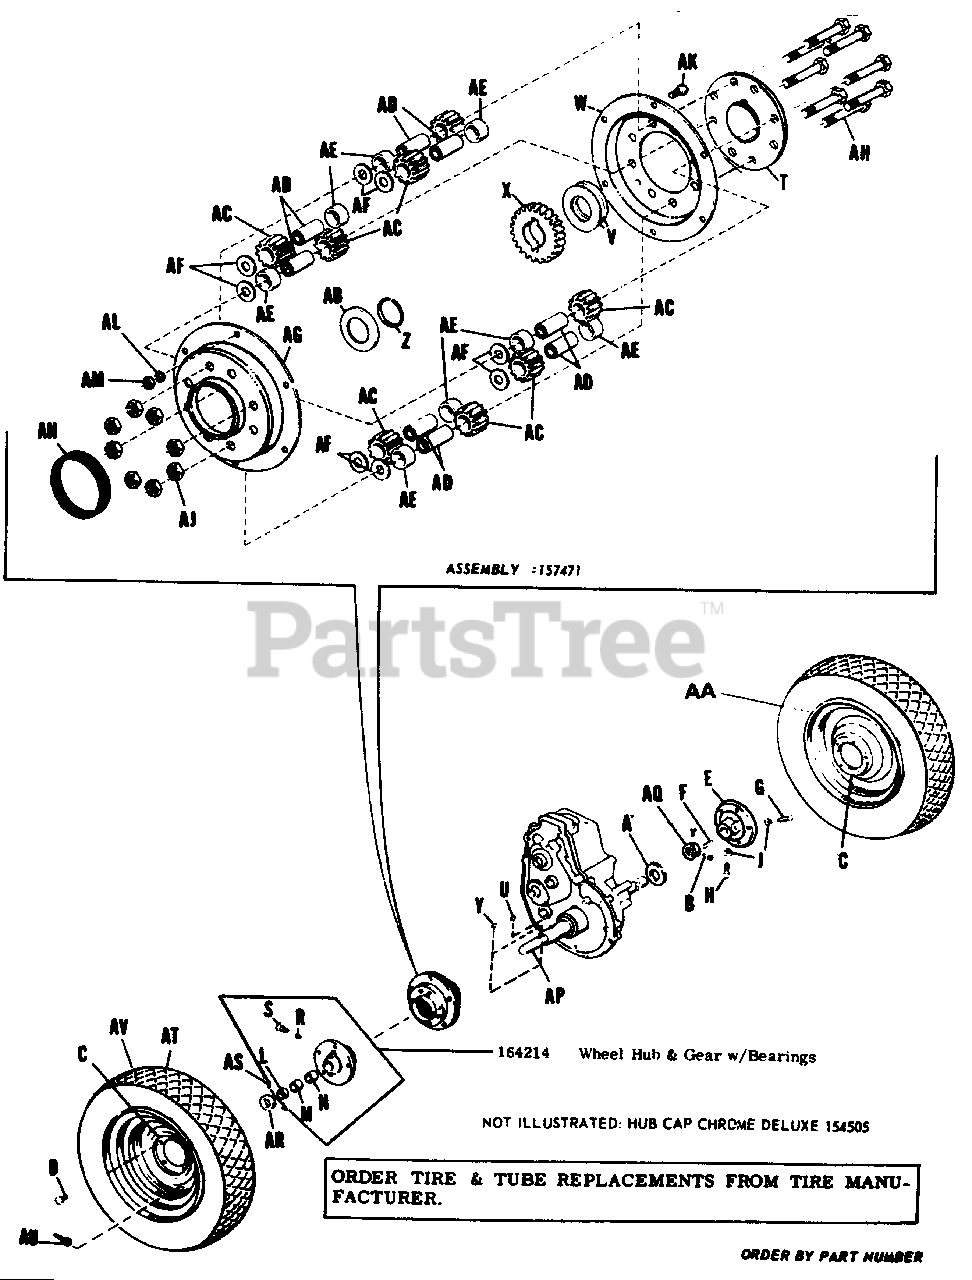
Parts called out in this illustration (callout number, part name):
B	Set Screw, 5/16"-18 x 3/8" Lg.
C	Wheel Drive
E	L.H. Wheel Hub
G	Set Screw, 3/8"-16 x 1 1/2" Lg.
H	Set Screw, 3/8"-16 x 1" Lg.
J	Hex. Jam Nut, 3/8"-16
M	Nylon Bearing
R	Nylon Plug
S	Control Traction Bolt, 7/16"-20 x 1/2" Lg.
T	Differential Carrier
V	Axle Washer
W	Differential Cover
X	Differential Gear
Y	Hi-Pro Key
Z	Retaining Ring
AA	Tube (For Service Only)
AB	Axle Washer
AC	Differential Pinion
AD	Pinion Differential Spindle
AE	Differential Spacer
AF	Plain Washer
AG	Differential Cover
AH	Hex. Cap Screw, 3/8"-16 x 2 1/2"
AJ	Full Lock Hex. Nut, 3/8"-16
AK	Hex. Cap Screw, 1/4 "-20 x 5/8"
AL	Lock Washer, 1/4"
AM	Full Hex. Nut, 1/4"-20
AN	Differential Cover Seal
AQ	Axle Collar
AR	Axle Collar
AS	Set Screw, 5/16"-18 x 3/8"
AT	Tire 10 1/2" x 12
AU	Valve Stem
AV	Wheel & Tire Assy.
